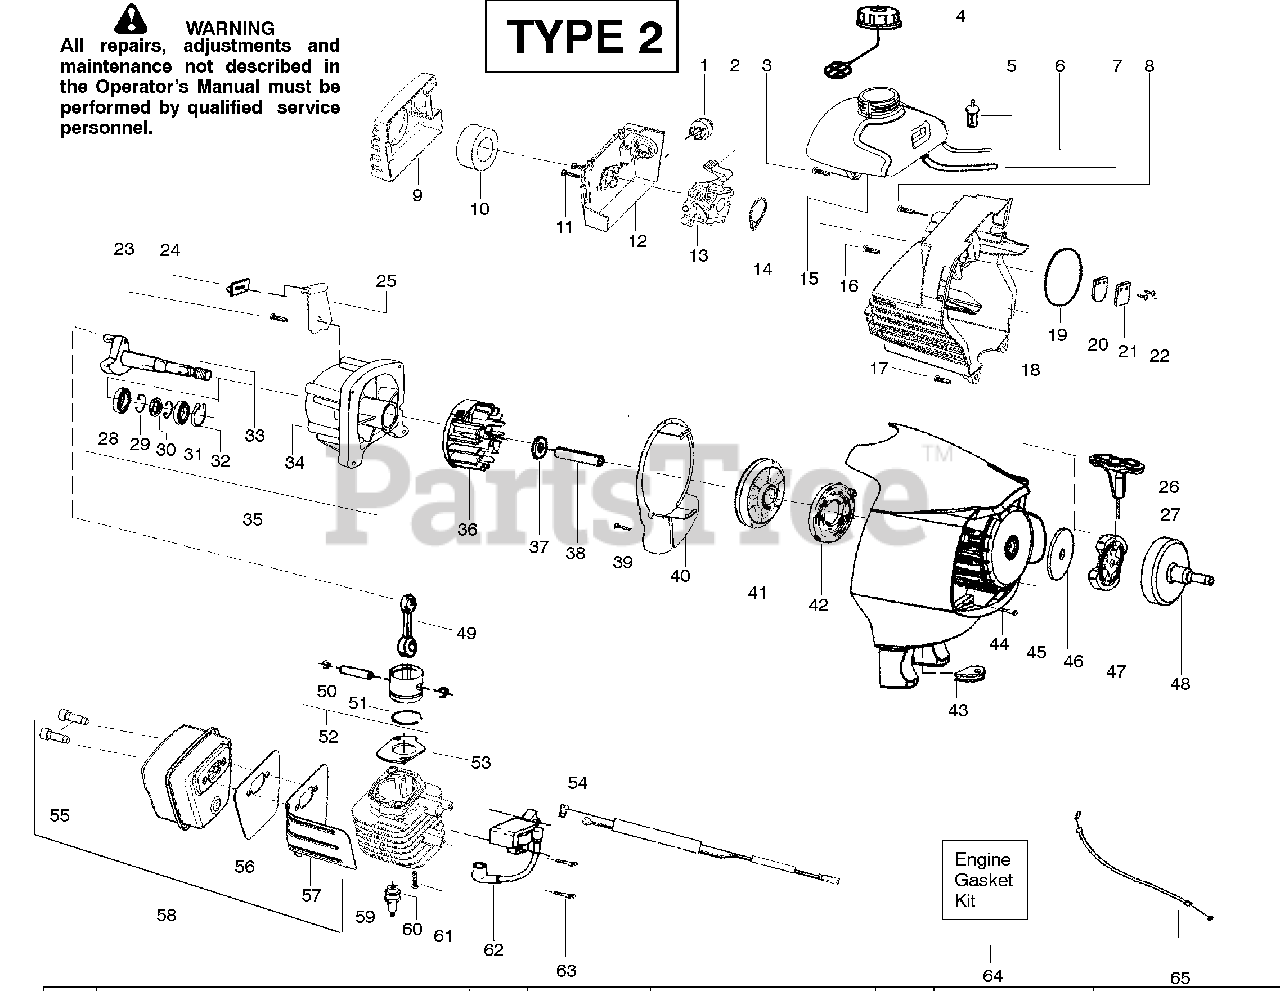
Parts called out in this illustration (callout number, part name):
2	Kit-Choke Lever
4	Cap-Fuel w/ret.
5	Assy-Fuel pickup
6	Kit-Fuel line
7	Kit-Fuel/Purge line
9	Cover-Air box
13	Kit-Carb assy. (C1U-W32)
14	Seal-Carb.(kit)
15	Assy-Fuel Tank
16	Screw-Crankcase
18	Assy-Rear Shroud
19	O-ring-Shroud (kit)
22	Screw-Reed stop
23	Screw-Retainer
24	Isolator-Tank
26	Handle-Starter
28	Bearing-Inner
31	Bearing-Outer
32	Ret.-Crankshaft
33	Assy-Crankshaft
34	Assy-Crankcase
35	Assy-C'case/C'shaf
36	Assy-Flywheel
42	Spring-Starter
44	Screw-F/hsg.
45	Assy-Fan Housing
46	Washer-Clutch
48	Assy-Drum/Adapter
49	Assy-Conn. Rod
50	Ret.-Piston pin
52	Kit-Piston
53	Gasket-Cylinder(kit)
54	Assy-Leadwire
55	Bolt-Muffler 1/4"-20
56	Gasket-Muffler (kit)
58	Kit-Muffler
60	Plug-Spark(RCJ-6Y)
61	Bolt-Cyl. 1/4"-20
62	Module-Ignition
64	Kit-Gasket/Seal
65	Assy-Throttle cable
